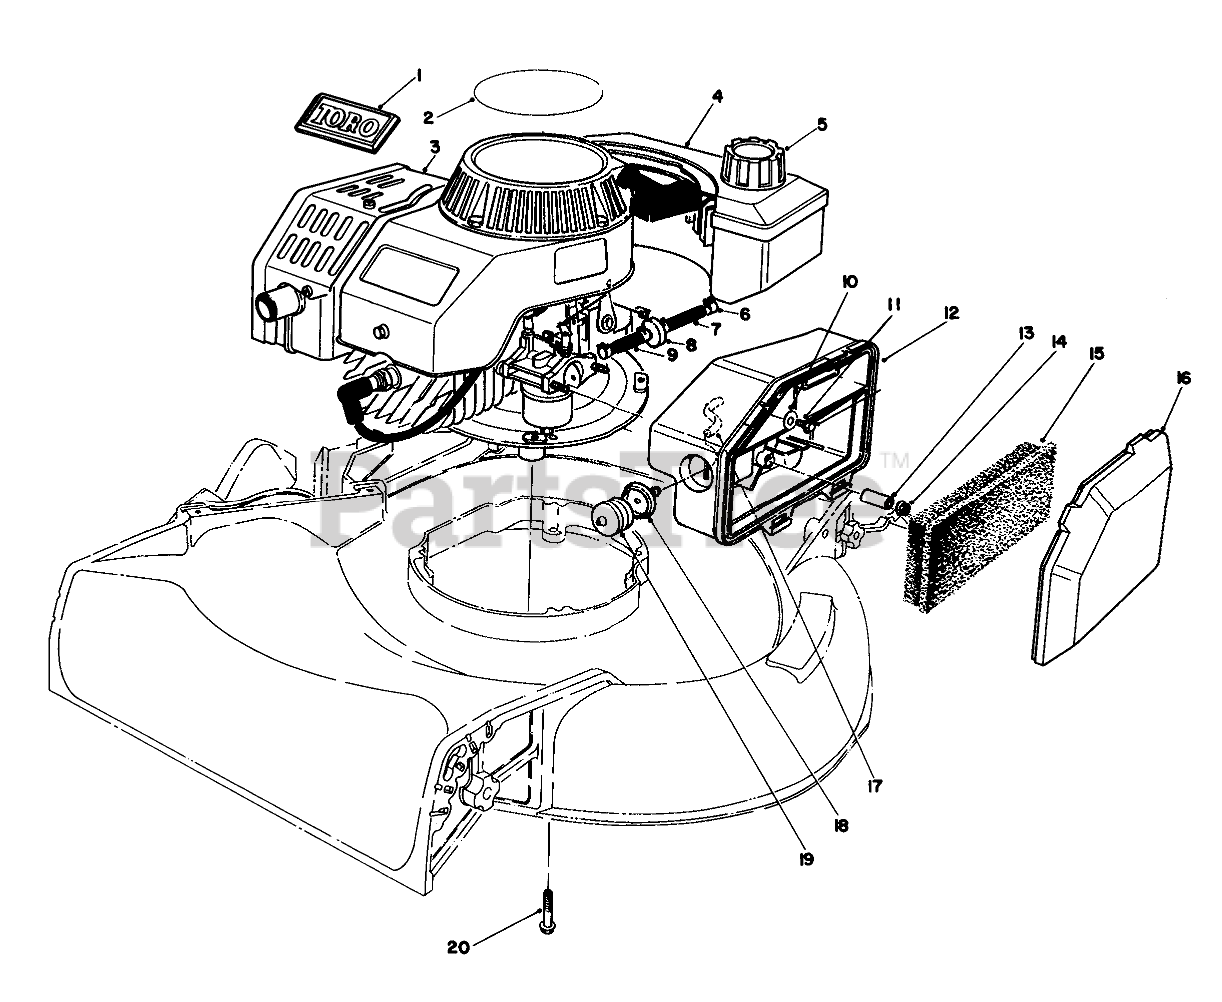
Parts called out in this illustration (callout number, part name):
1	TORO LOGO PLT
2	DECAL- 2 CYC RECOIL
3	Engine (Complete)
4	FUEL TANK ASM
5	GAS CAP ASM
6	CLAMP-FUEL LINE
7	HOSE-FUEL
8	FILTER-FUEL
9	HOSE-FUEL
10	WASHER-FLAT
11	SCREW-HH
12	BODY-AIR CLEANER
13	SPACER
15	ELEMENT-AIR CLEANER
16	COVER-AIR CLEANER
17	HOSE-PRIMER
18	BODY-PRIMER
19	Bulb Primer
20	FLG SCREW,3/8-16X2.000
